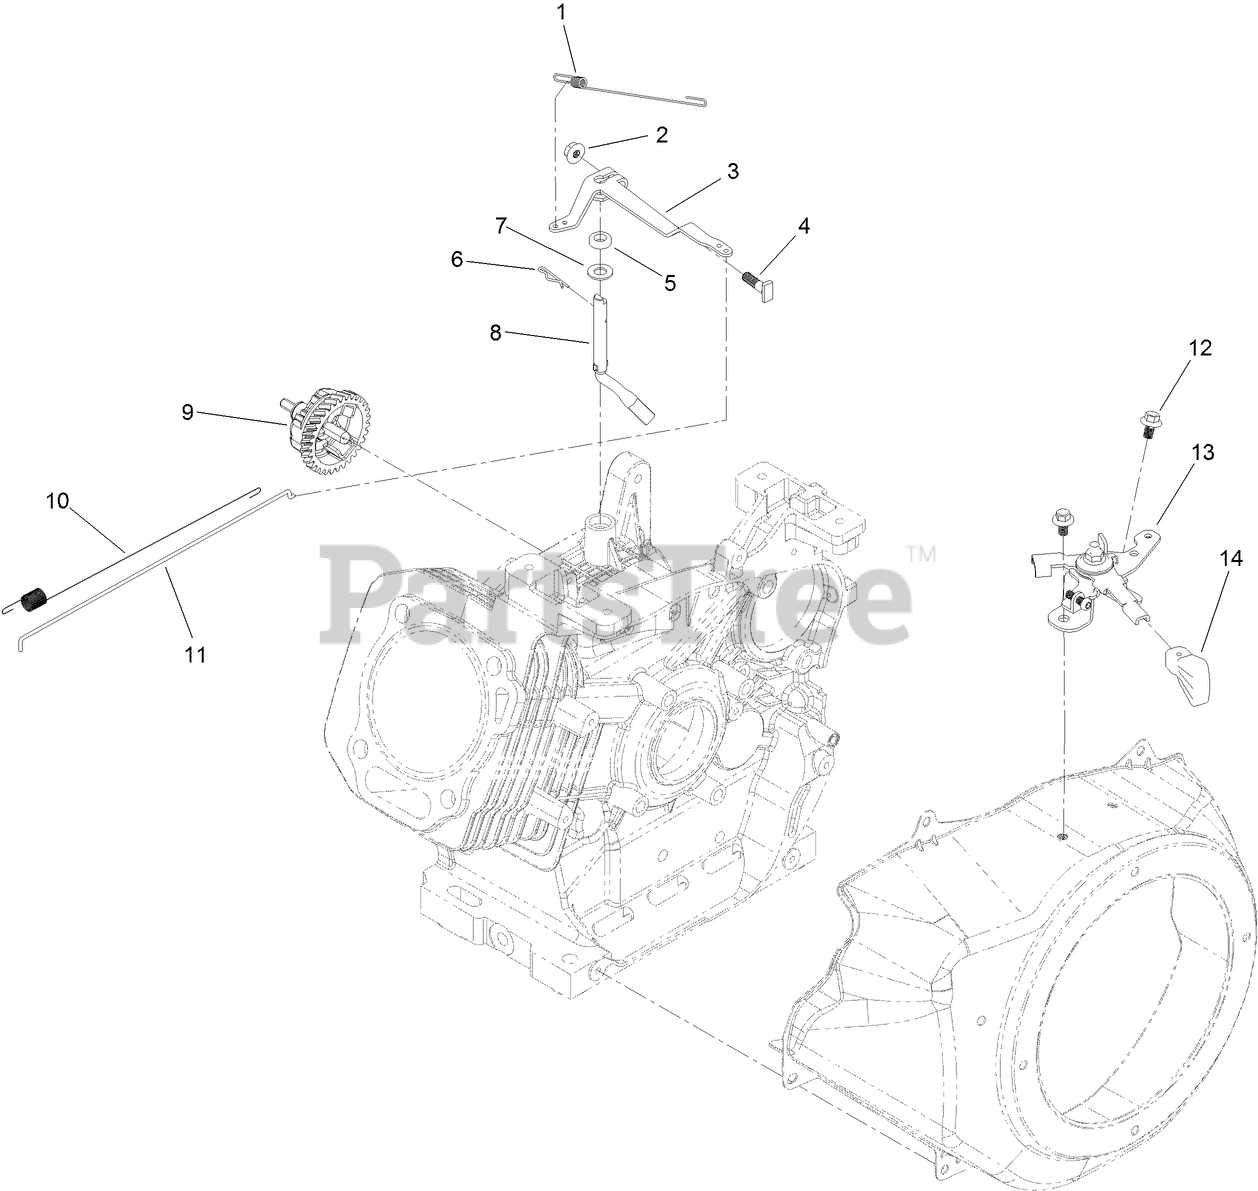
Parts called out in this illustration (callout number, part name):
1	SPRING-GOVERNOR
2	NUT-FLANGE
3	ARM-GOVERNOR
4	BOLT-ARM, GOVERNOR
5	SEAL-OIL
6	PIN-HAIR
7	WASHER-PLAIN
8	SHAFT-GOVERNOR
9	GOVERNOR GEAR ASM
10	SPRING-RETURN, THROTTLE
11	ROD-GOVERNOR
12	SCREW-HHF
13	THROTTLE CONTROL ASM
14	KNOB-CONTROL, THROTTLE
